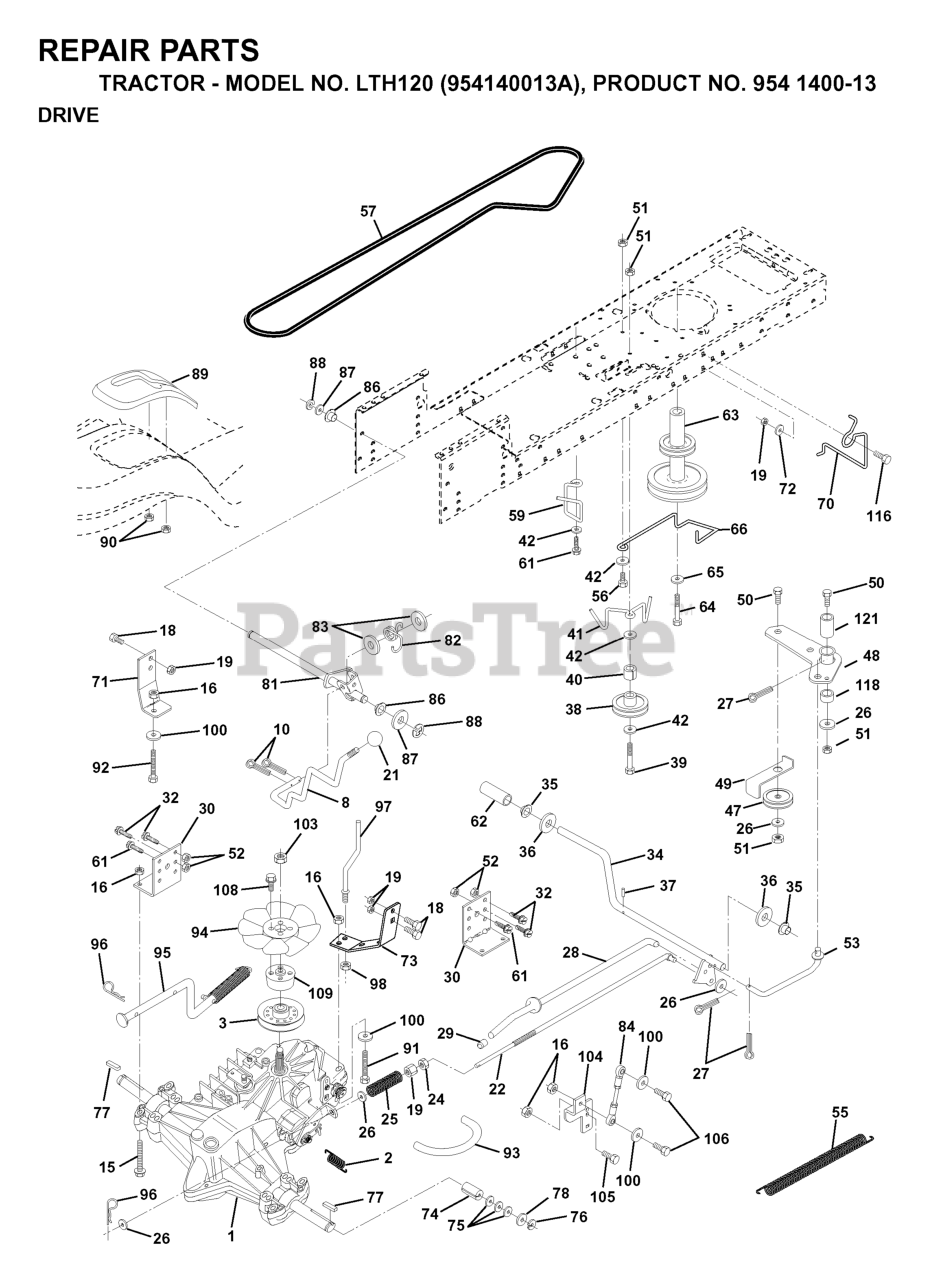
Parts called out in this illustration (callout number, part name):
1	TRANSAXLE.HYDRO.319-0500.LR
2	SPRING BRAKE
3	PULLEY.4.20.HYDRO
8	ROD SHIFT FENDER
10	PIN COTTER
15	BOLT HEX 5/16-18 GR 5
16	NUT.71038.31-18.HEX.NYLOCK
19	NUT
21	KNOB T (1/2-HOLE)
22	ROD BRAKE HYDRO
24	NUT
25	SPRING ROD LT
26	WASHER
27	COTTER PIN
28	ROD BRAKE PARK LT
29	PLUNGER CAP
30	BRACKET TRANSAXLE
32	BOLT
34	SHAFT, FOOT PEDAL
35	BEARING.NYLON
37	DRIVE PIN
38	PULLEY.IDLER.FLAT
41	KEEPER, BELT IDLER
42	WASHER
47	IDLER PULLEY
48	BELLCRANK ASSEMBLY
49	RETAIN BELT
50	BOLT
52	LOCKNUT
53	LINK, CLUTCH LT
55	SPRING, RETURN LT
59	KEEPER CENTER SPAN
61	SCREW
62	PEDAL COVER T
63	PULLEY.ENG.CL.MECH.SLVR.LT/YT
64	BOLT
65	LOCKWASHER
66	KEEPER BELT ENGINE
70	KEEPER BELT ENG
71	STRAP TORQUE LH HYDRO
72	WASHER
73	STRAP TORQUE RH HYDRO
74	SPACER SPLIT
77	SQUARE KEY
81	SHAFT ASM CROSS HYDRO
82	SPRING,TORSION
83	WASHER
84	ROD, TIE HYDRO
86	BUSHING.STEERING.ROD LTB-WSL
89	CONSOLE SHIFT
90	NUT.PUSH.3/16
91	BOLT.FIN HEX 5/16-18UNC X2 1/4
92	HEX BOLT
93	LINE FUEL HYD 4"
94	FAN 7" HYDRO
95	CONTROL ARM, BYPASS HYDRO
96	RETAINER M
97	KEEPER BELT RH
100	WASHER M
103	NUT.HEX.1/2-20
104	ARM, CONTROL HYDRO
106	BOLT.5/16-18X1-1/4 FULL.THREAD
109	ADAPTOR FAN HYDRO
116	BOLT
118	SPACER BELLCRANK
121	NYLINER CLUTCHING
